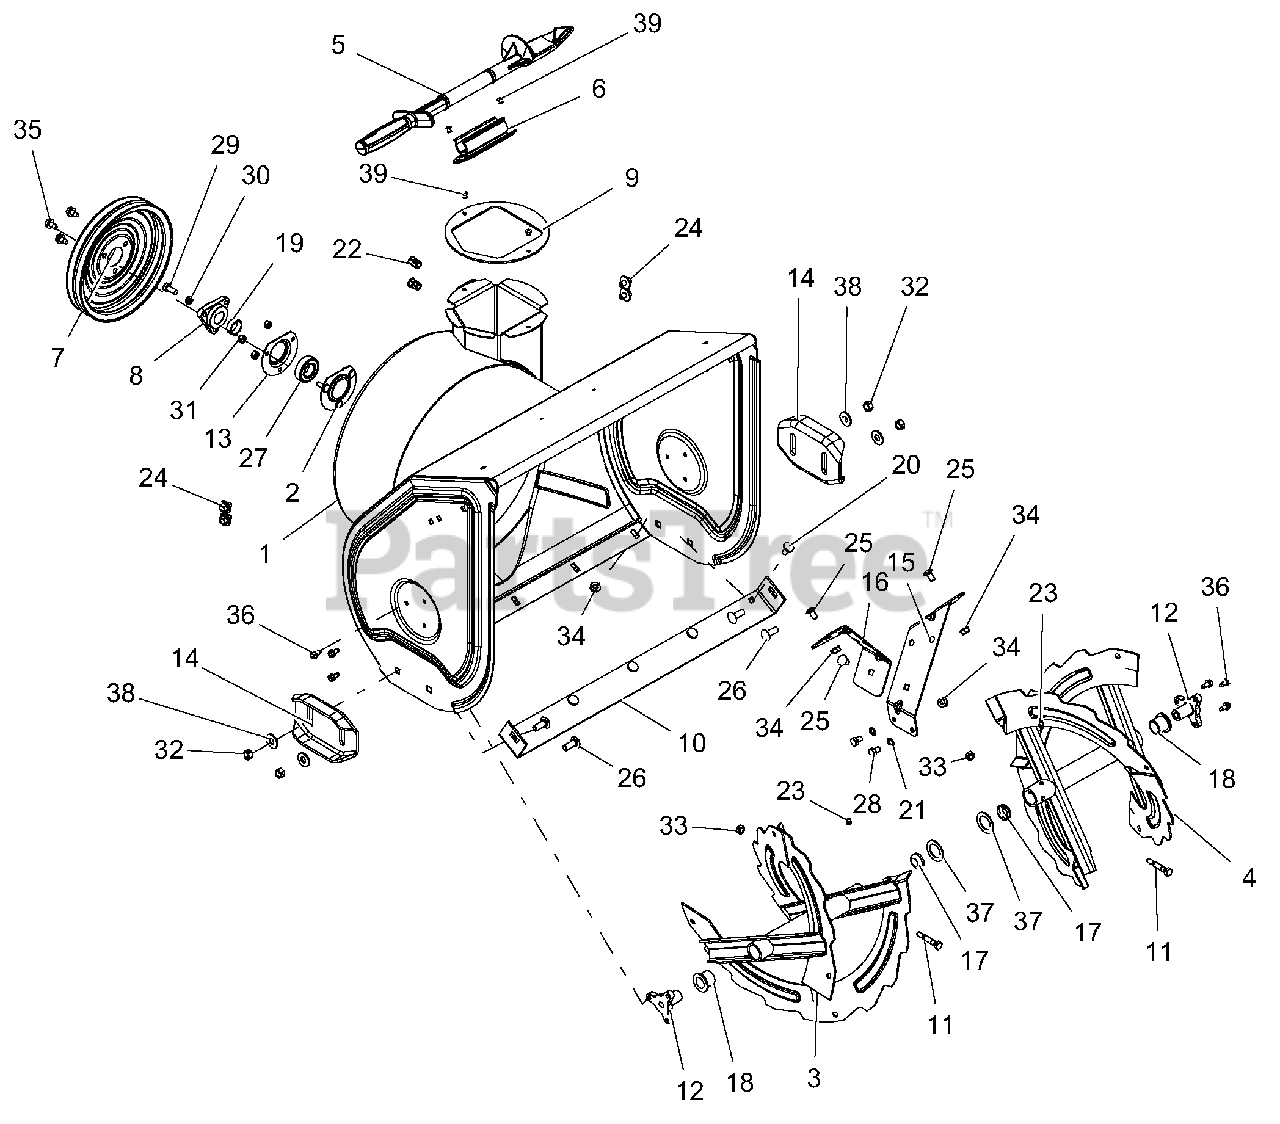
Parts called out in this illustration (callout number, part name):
1	BLOWER HOUSING W/DECAL 24"
2	BEARING FLANGE
3	RAKE, RH W/ZERK - 24"
4	RAKE, LH W/ZERK - 24"
5	DEVICE, SNOW CLEAN OUT
6	MOUNT, SNOW CLEAN OUT
7	PULLEY, SPIN FORM DUAL GROOVE
8	PULLEY HUB, D-BORE .87 DELUXE
9	BAFFLE, DISCHARGE NECK
10	BLADE, SCRAPER-24"
11	SHEAR BOLT SERVICE ASSEMBLY
12	SUPPORT, RAKE BUSHING
13	BEARING FLANGE
14	SKID SHOE, REVERSIBLE - ORANGE
15	BRACKET, GEARCASE SUPPORT - LH
16	BRACKET, GEARCASE SUPPORT - RH
17	PLUG, RAKE TUBE
18	BSHG-FLG, NY.778 ID X 1.018 OD
19	BSHG-SPCR .895IDX1.065ODX.353
20	BOLT, MODIFIED HEAD CARRIAGE
21	@WSHR-LK-EXT.326X.599X.031YWZC
22	NUT, THREADED INSERT .38-16
23	ZERK,FITTING .25X.125 DRIVE IN
24	SCR-TAP.31-18X.50 HWH TR YWZ
25	BLT-RDHDSQSHNK.31-18X.62 YZ-LK
26	@BLT-RDHDSHSQNK.38-16X1.0 G5YZ
27	BRG-BALL .876X1.75X.50 RSTFP
28	@BLT-HEX .31-18X.50 GR5 YWZC
29	BLT-HEX .31-24X.75 YWZC GR5
30	WSHR-LK .312X.097 HVY YWZC
31	@NUT-LK-CTR .25-20 YWZC
32	@NUT-LK-CTR .38-16 YWZC
33	@NUT-LK-CTR .31-18 YWZC
34	@NUT-LK-TOP-FLG .31-18 YWZC
35	@SCR-TAP .31-18X.50 HWH TR YWZ
36	SCR-TAP .25-20X.50 HWH TR YWZ
37	WSHR-FL-STL 1.010X1.505X.062YZ
38	@WSHR-FL-STL.438X1.00X.083 YWZ
39	RVT-POP .187 YZ
